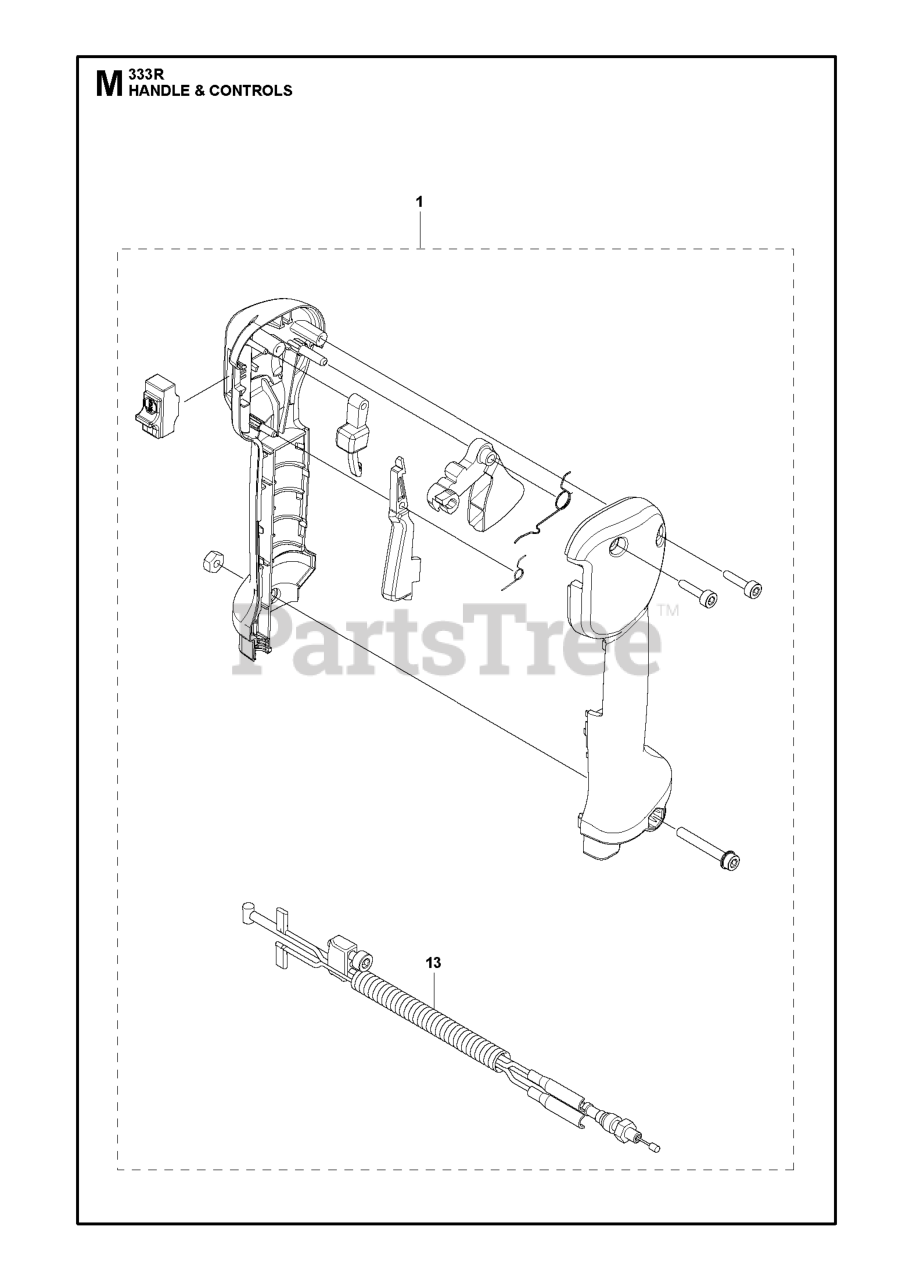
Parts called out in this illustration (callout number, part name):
2	VALVE STEM LT
3	FITTING LT
4	TIRE FRONT 15X6-6
5	TUBE.5.3/4.5/6
5	TUBE.16X6.5/7.5-8
6	RIM REAR 8"
6	RIM
7	CAP.HUB.FRONT.LT.BLACK
8	BEARING T
